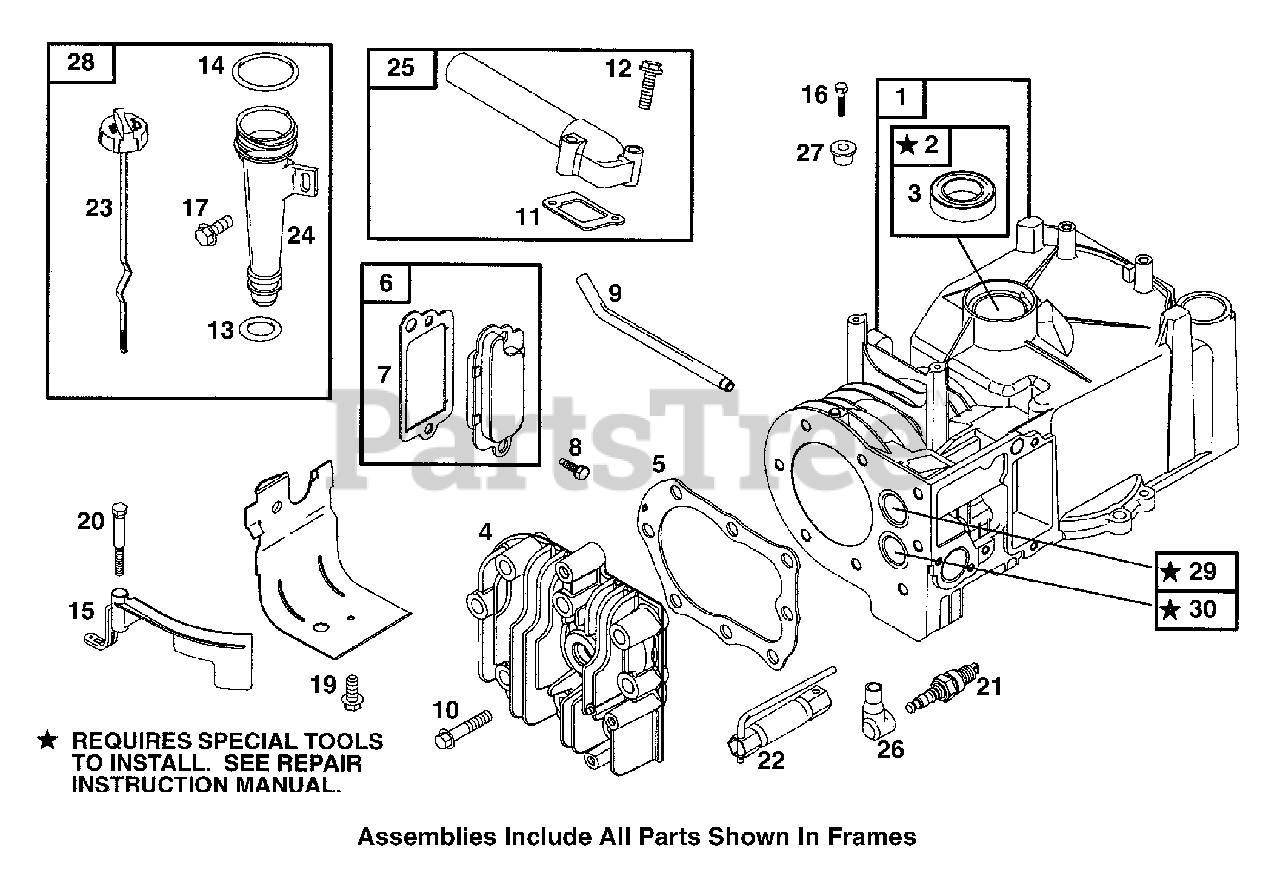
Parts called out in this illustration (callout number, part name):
1	Cylinder Assembly
2	Bushing
3	Oil Seal
4	Cylinder Head
5	Cylinder Head Gasket
6	Breather Assembly
7	Breather Gasket
8	Hex Screw
9	Breather Tube
10	Hex Screw
11	Gasket-Intake
12	Hex Screw
13	Seal-O-Ring
14	Seal-O-Ring
15	Blade-Governor
16	Hex Screw
17	Shoulder Screw
19	Hex Screw
20	Shoulder Screw
21	Spark Plug
22	Spark Plug Wrench
24	Oil Fill Tube
25	Manifold-Intake
26	Spark Plug Boot
28	Dipstick/Tube Ass’y
29	Valve Seat (Intake)
30	Valve Seat (Exhaust)
